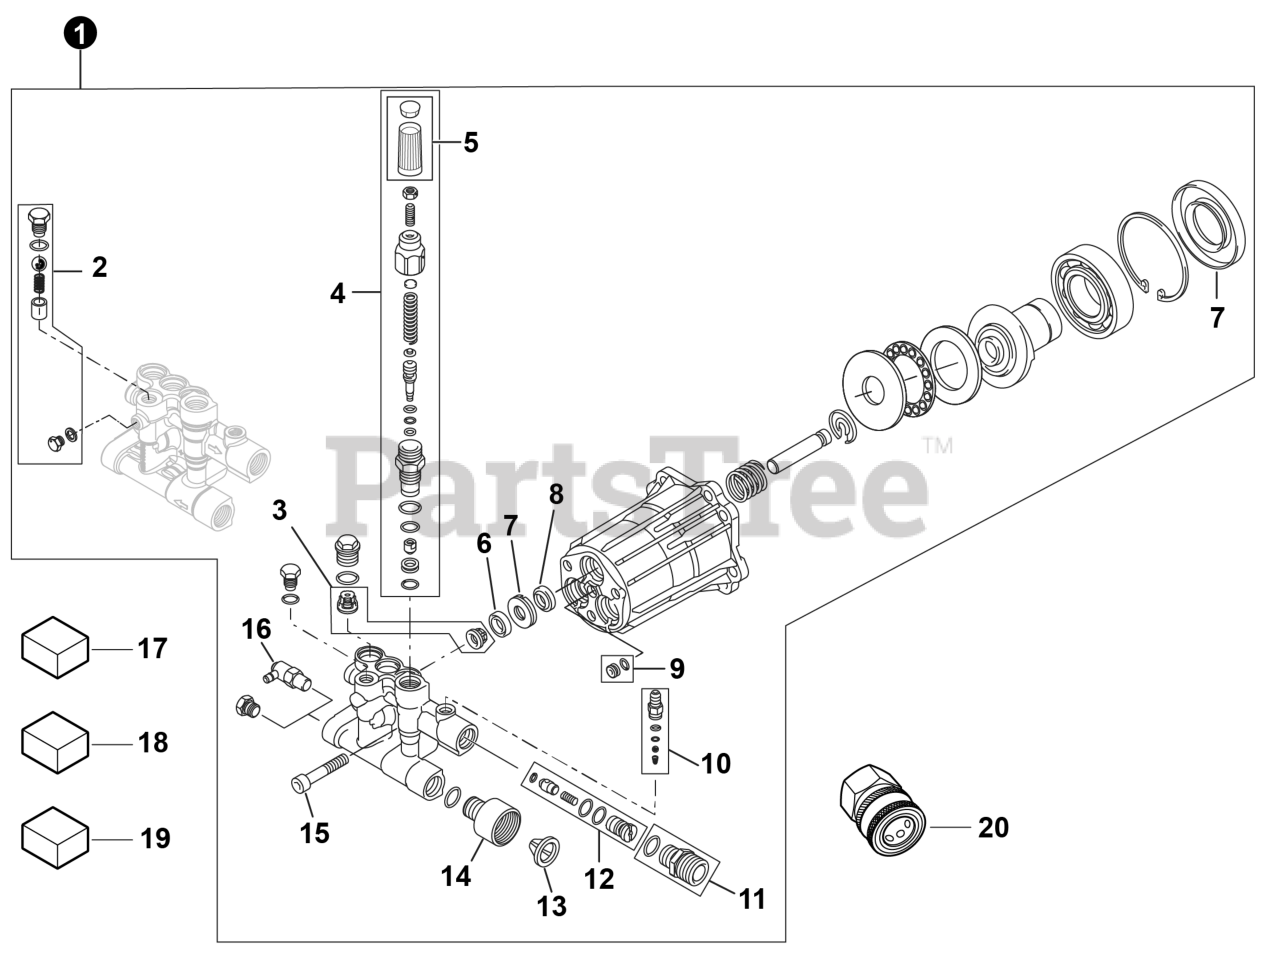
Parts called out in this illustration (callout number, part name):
1	PUMP ASSY.
2	KIT, EZ START
3	KIT, VALVE
4	KIT, UNLOADER
5	KNOB,ADJUSTMENT
6	KIT, WATER SEAL
8	KIT, OIL SEAL
9	OIL PLUG W/O-RING
10	KIT, INJECTOR
11	OUTLET FITTING W/O-RING
12	CHECK VALVE ASSEMBLY
13	FILTER, INLET SCREEN
14	ADAPTOR, GARDEN HOSE INLET
15	BOLT, PUMP MOUNTING W/WASHER
16	VALVE, THERMAL RELIEF
17	KIT, O-RING
18	O-RING, 1/4" - 100 Pack
19	O-RING, 3/8" - 100 Pack
20	3/8" FNPT Q/C
